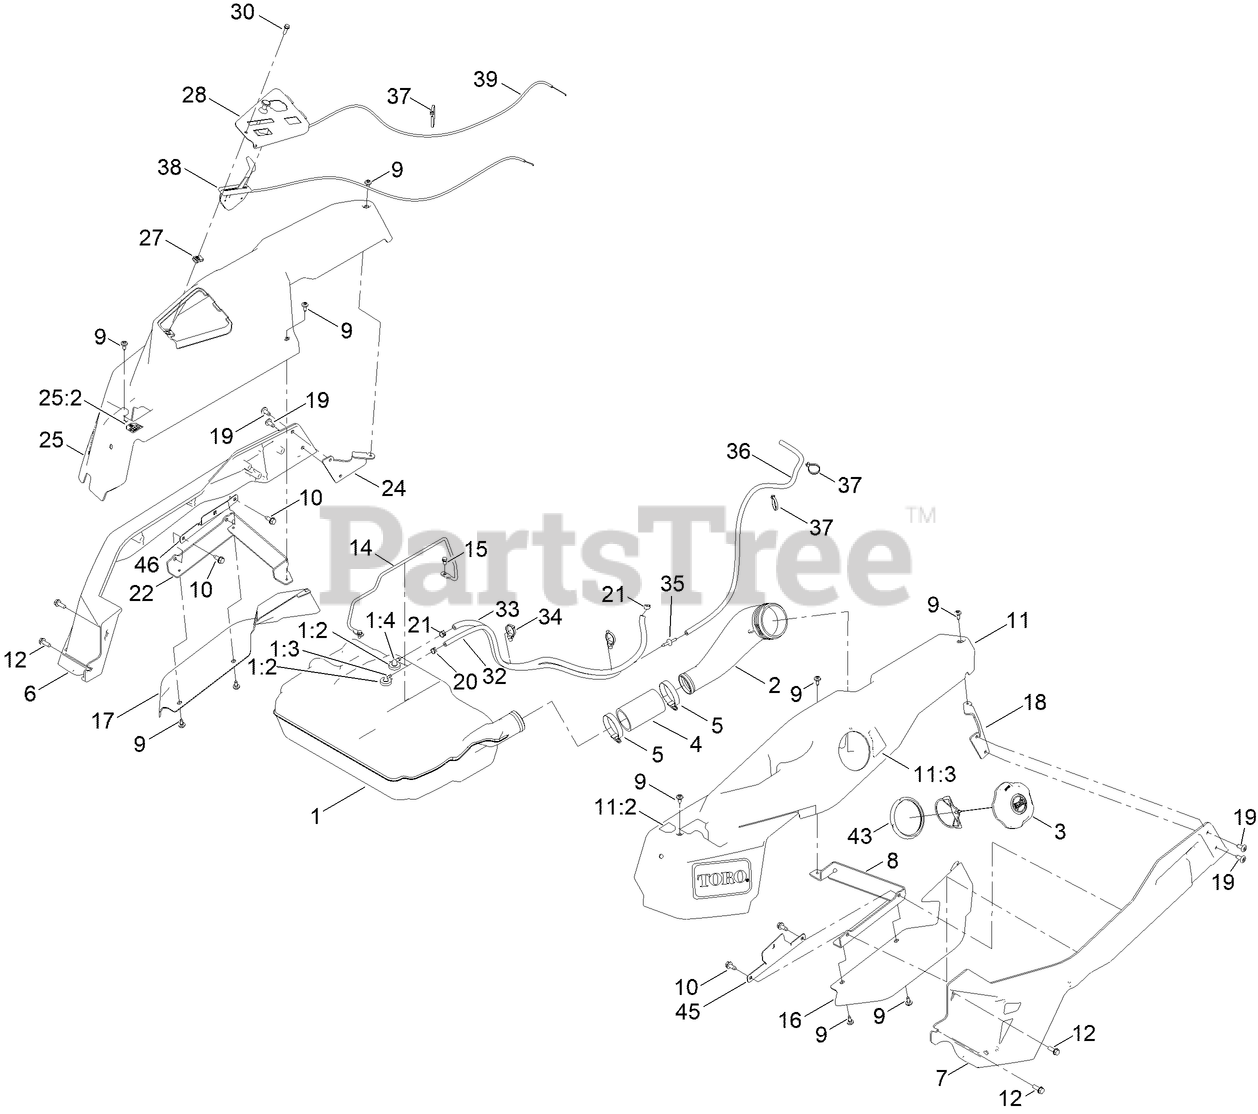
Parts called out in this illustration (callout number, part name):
1	TANK-FUEL ASM
1:2	BUSHING
1:3	FITTING-ELBOW 90
1:4	FITTING - PICKUP, FUEL
2	NECK-FILLER, FUEL
3	CAP-FUEL, RATCHETING
4	HOSE-FILLER, FUEL
5	CLAMP-HOSE
6	CAST-TUBE, RH [BLK-TXT]
7	CAST-TUBE, LH [BLK-TXT]
8	MOUNT-POD BRACKET LH
9	SCREW-SHOULDER
10	SCREW-HWHTF
11	POD ASM - LH W/DECALS
11:2	DECAL-CONTROL LEVER, LH
11:3	DECAL-FUEL FILL
12	SCREW-TAPTITE
14	ROD-HOLD DOWN
15	SCREW-HWH
16	FENDER-TIME CUTTER, LH
17	FENDER-TIME CUTTER, RH
18	BRACKET-REAR POD, LH
20	CLAMP-HOSE
21	CLAMP-HOSE
22	MOUNT-POD BRACKET RH
24	MOUNT-POD BRACKET RH
25	POD ASM - RH W/DECALS
25:2	DECAL-CONTROL LEVER, RH
28	PANEL-CONTROL
30	SCREW-HWH
32	HOSE-FUEL
33	HOSE-FUEL
34	CLIP-TIE
35	ADAPTER ORIFICE
36	HOSE-LP
37	TIE-CABLE
38	CABLE-THROTTLE
39	CABLE-CHOKE
43	RING-RETAINING
45	BRACKET-ALIGNMENT, POD LH
46	BRACKET- ALIGNMENT, POD RH
